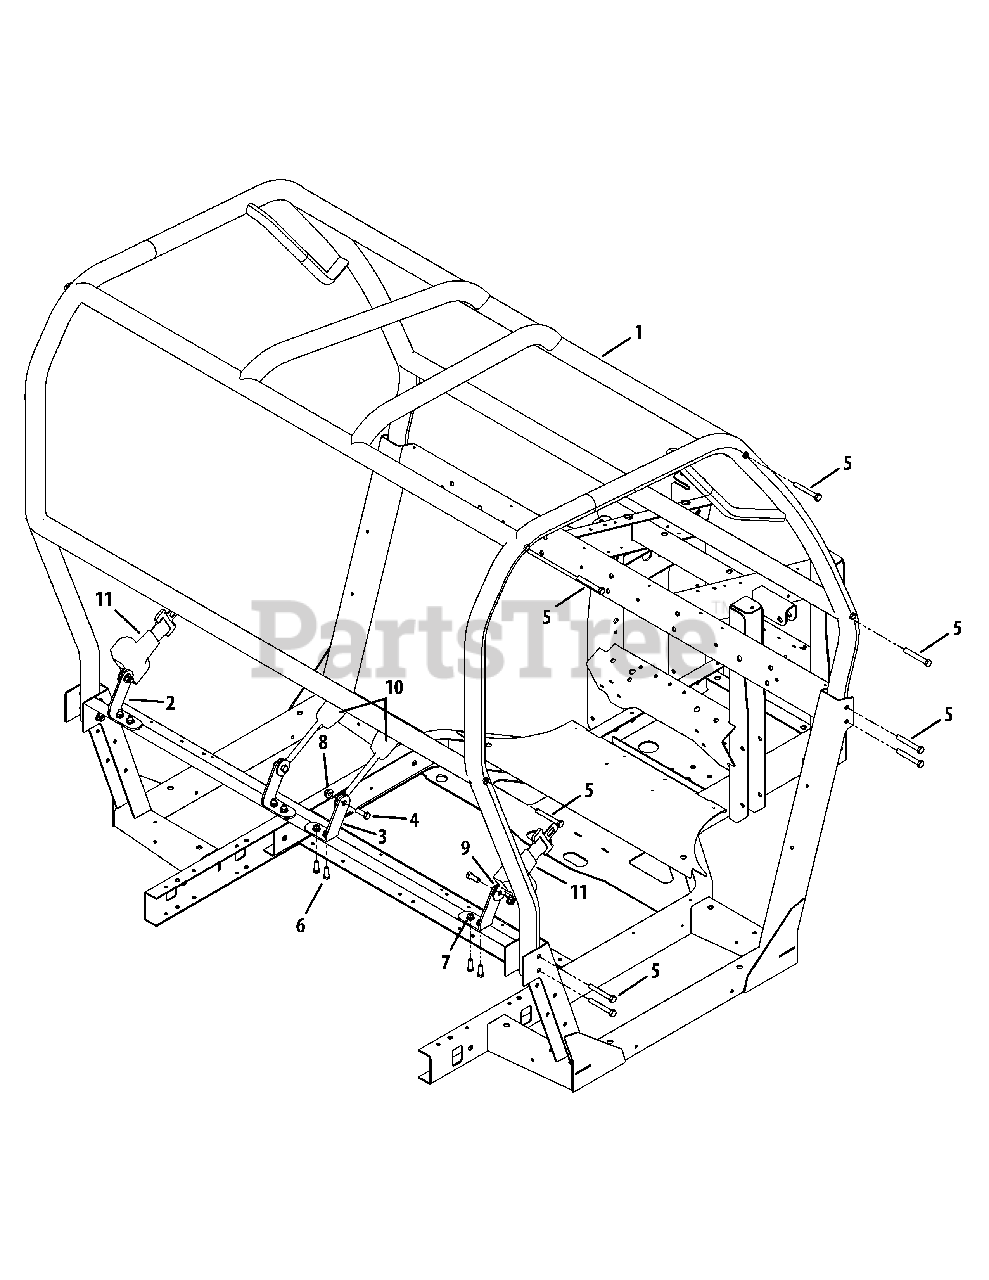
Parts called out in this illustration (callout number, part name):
1	Frm Assembly, OPS, UV
4	Screw, 3/8-16 x 1.00
5	Screw, 3/8-16 x 2.75
6	Scew, 5/16-18 x .875
7	Nut, Flglk, 5/16-18
8	Nut, Flglk, 3/8-16
9	Wash, Flat, .406 x 1.5 x .105
10	Belt, Seat
11	Belt, Seat
